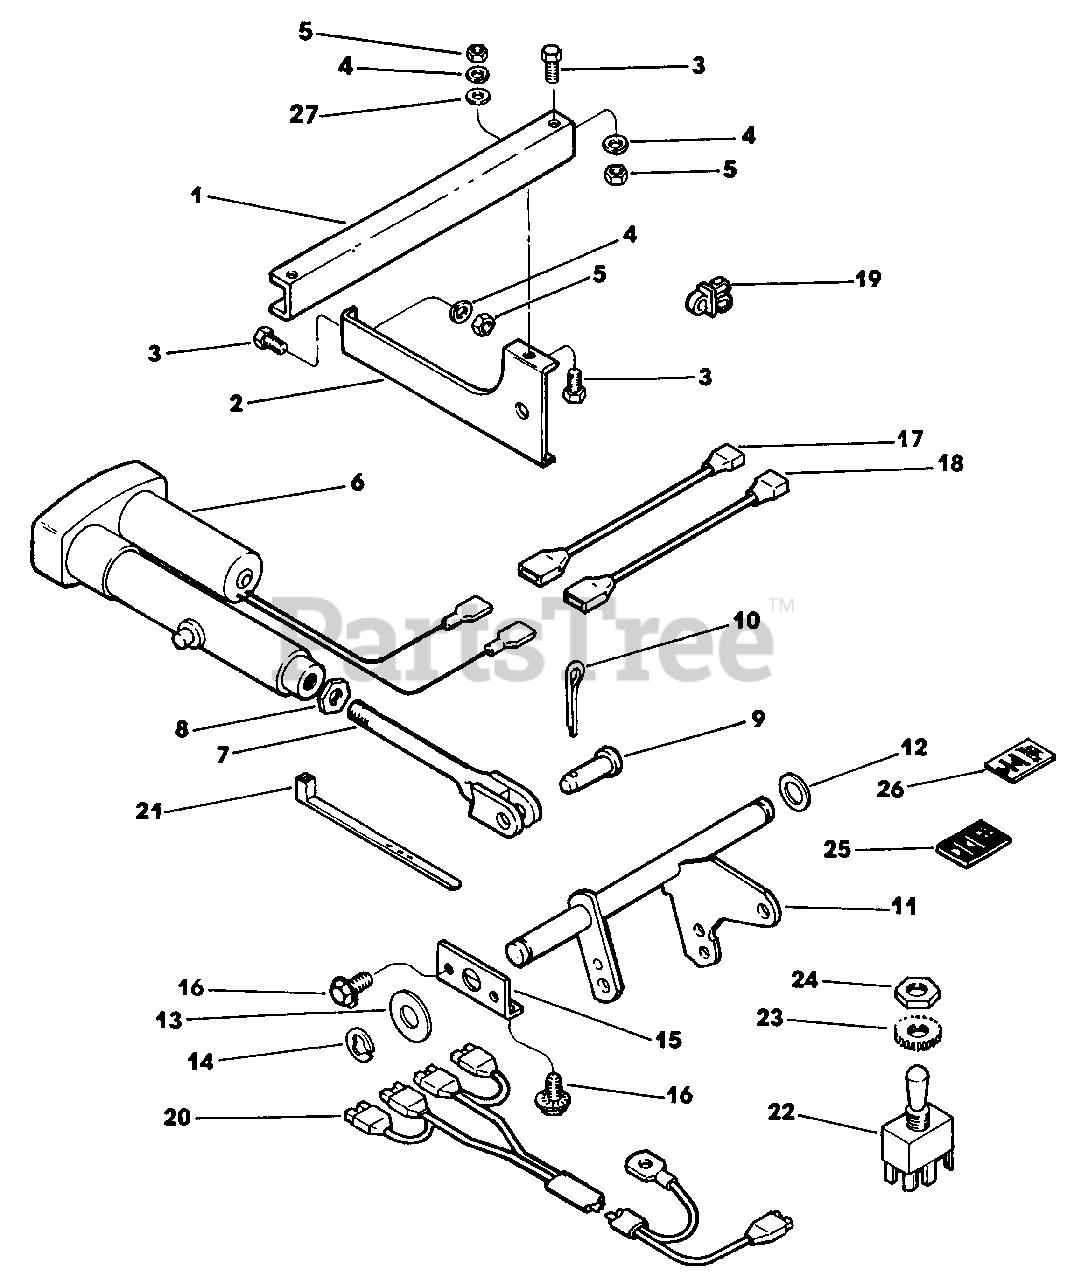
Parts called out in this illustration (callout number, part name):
2	Support
3	Cap Screw, Hex Hd
4	Washer, Spring Lock
5	Nut, Hex
6	Power Lift Assembly
7	Rod Assembly
8	Nut, Hex
9	Clevis Pin
10	Pin, Cotter
11	Lift Shaft Assembly
14	"E" Ring
15	Lift Bracket
16	Thread Forming Screw, Hex Hd
17	Wire, Yellow-37"
18	Wire, Red-37"
19	Wire Clip
20	Wiring Harness
21	Cable Tie
22	DPDT Switch
23	Knurled Nut
24	Hex Nut
25	Decal-Electric Lift (White On Black)
26	Electric Lift (Black On Silver)
27	Washer, Flat
